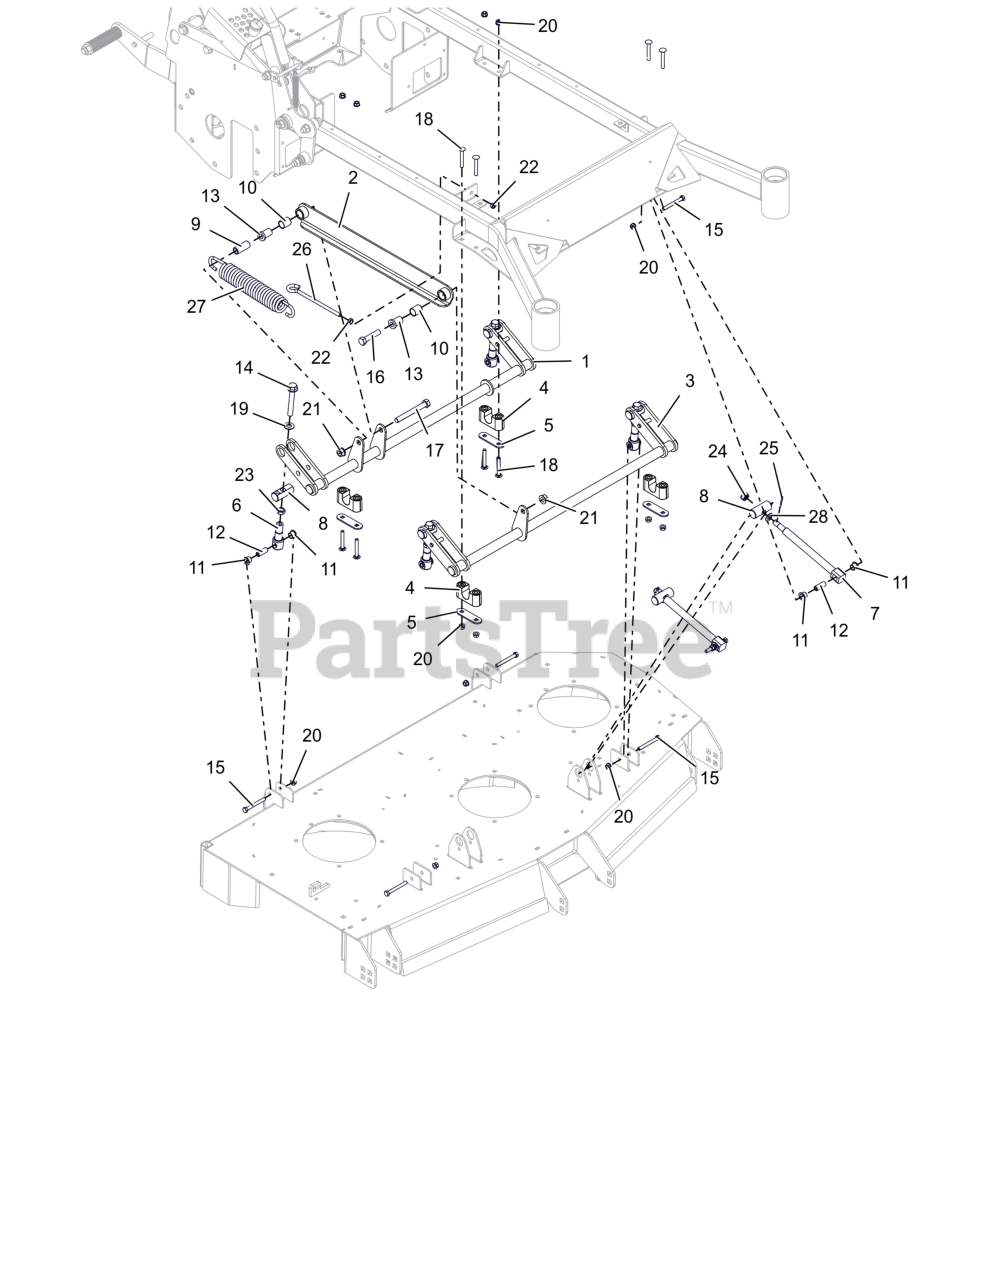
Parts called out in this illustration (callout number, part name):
1	WLDMT, DECK LIFT
2	LINK, DECK LIFT
3	WLDMT, FRONT DECK LIFT (BLACK)
4	ASM-BUSHING, DECK LIFT
5	PLATE, BEARING SUPPORT
6	LINK, DECK LIFT FORMED
7	DRAG,LINK-HD
8	PIN, DECK LIFT
9	BSHG, FLANGE .515 X .750 X 1.544 X 1.000
10	BRG, .750 X .875 X 1.000
11	BSHG, FLANGED .50X.625X.50X.062
12	SPCR, .31X.50X1.265
13	BSHG-FLG .515X.746X1.290X1.000
14	BLT, .500-13 X 3.500 GR5 ZC
15	BLT, HEX .31-18X2.75 G5 ZCC
16	BLT, HEX .50-13X2.25 G5 ZCC
17	BLT, HEX 0.5-13X4.25 GR5 ZCC
18	BLT, RHSSN.31-18X2.25 G5 ZCC
19	WSHR, FLT .557X1.040X.102 ZCC
20	NUT,LK-CTR-FLG .31-18 GF ZCC
21	NUT-LK-CTR-FLG .500-13 GG ZCC
22	NUT-JAM .375-16 G2 ZCC
23	NUT-JAM .500-13 G2 ZCC
24	NUT-SL .50-13
25	PIN,CTR.12X1.25EXTPRSQCT ZC120
26	BOLT, .38-16X6.00 .62 DIA EYE
27	SPRG, EXTENSION - .273X1.853X.10.125
28	WSHR, BLVL .505 X 1.000 X .073 ZCC
